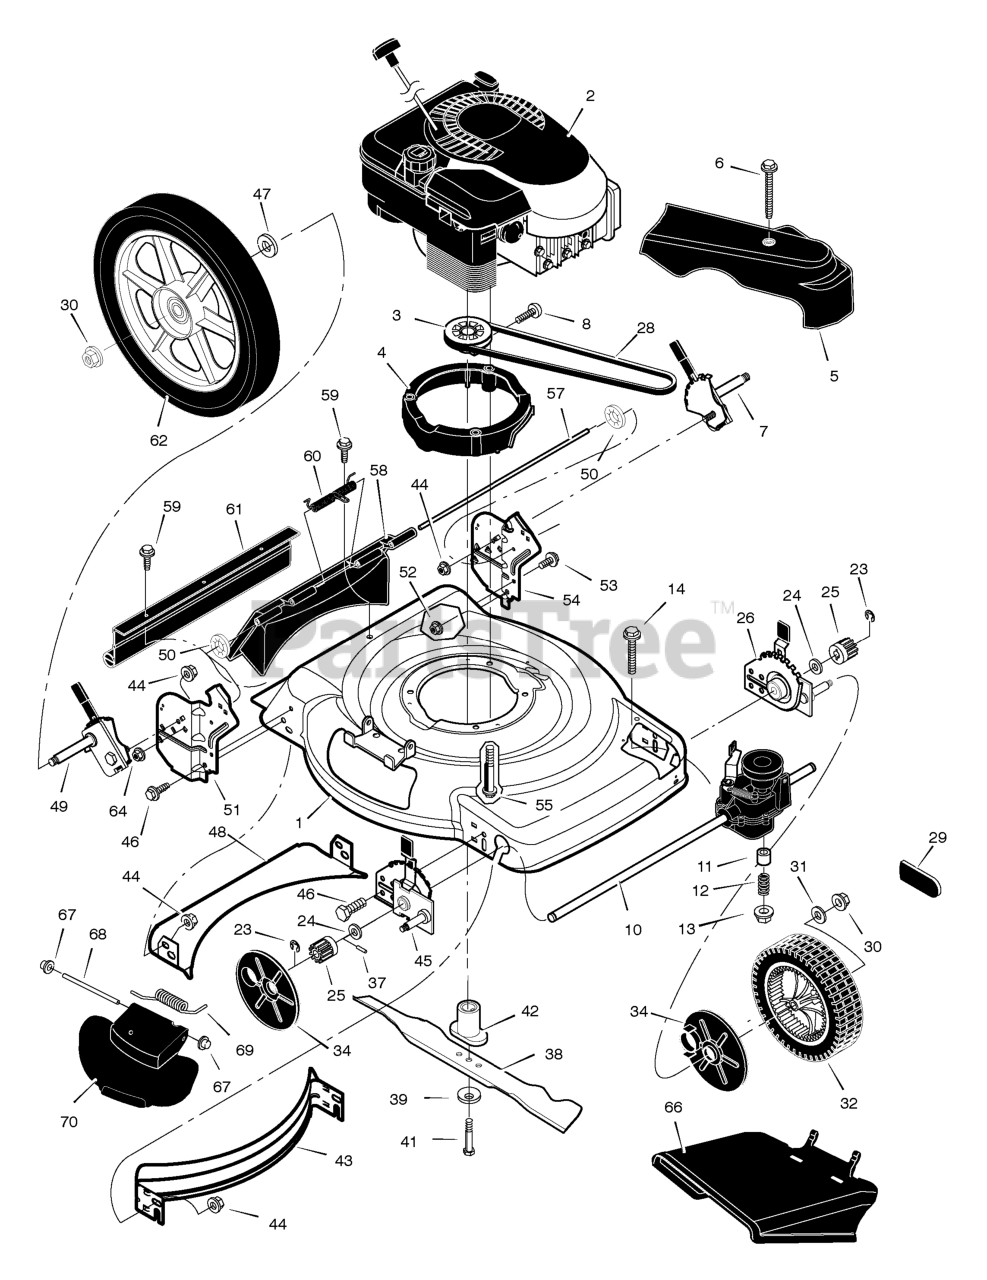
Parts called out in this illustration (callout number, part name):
2	Engine *
3	Pulley, Drive
4	Spacer, Engine
5	Cover, Belt (Black)
6	Screw
7	Adjuster, Left Rear Height
8	Screw
10	Transmission *
12	Spring, Compression
13	Nut
14	Bolt
25	Gear, Pinion
26	Adjuster, Left Front Height
29	Cap, Hub (Gray)
30	Nut, Flange
31	Washer
32	Wheel & Tire, Front (Gray)
34	Cover, Dust
37	Pin, Drive
38	Blade
39	Washer, Belleville
42	Adapter, Blade
43	Baffle, Front
44	Nut, Flange
45	Adjuster, Right Front Height
46	Bolt
48	Baffle, Rear
49	Adjuster, Right Rear Height
50	Retainer, Push
51	Bracket, Right Handle
52	Nut, Flange
53	Bolt
54	Bracket, Left Handle
55	Bolt, Engine
57	Rod, Pivot
58	Door, Rear (Black)
60	Spring
61	Guard, Rear
62	Wheel & Tire, Rear (Gray)
64	Nut
66	Deflector, Chute (Black)
67	Push On Cap
68	Rod, Pivot
69	Spring, Torsion
70	Cover, Mulch (Black)
